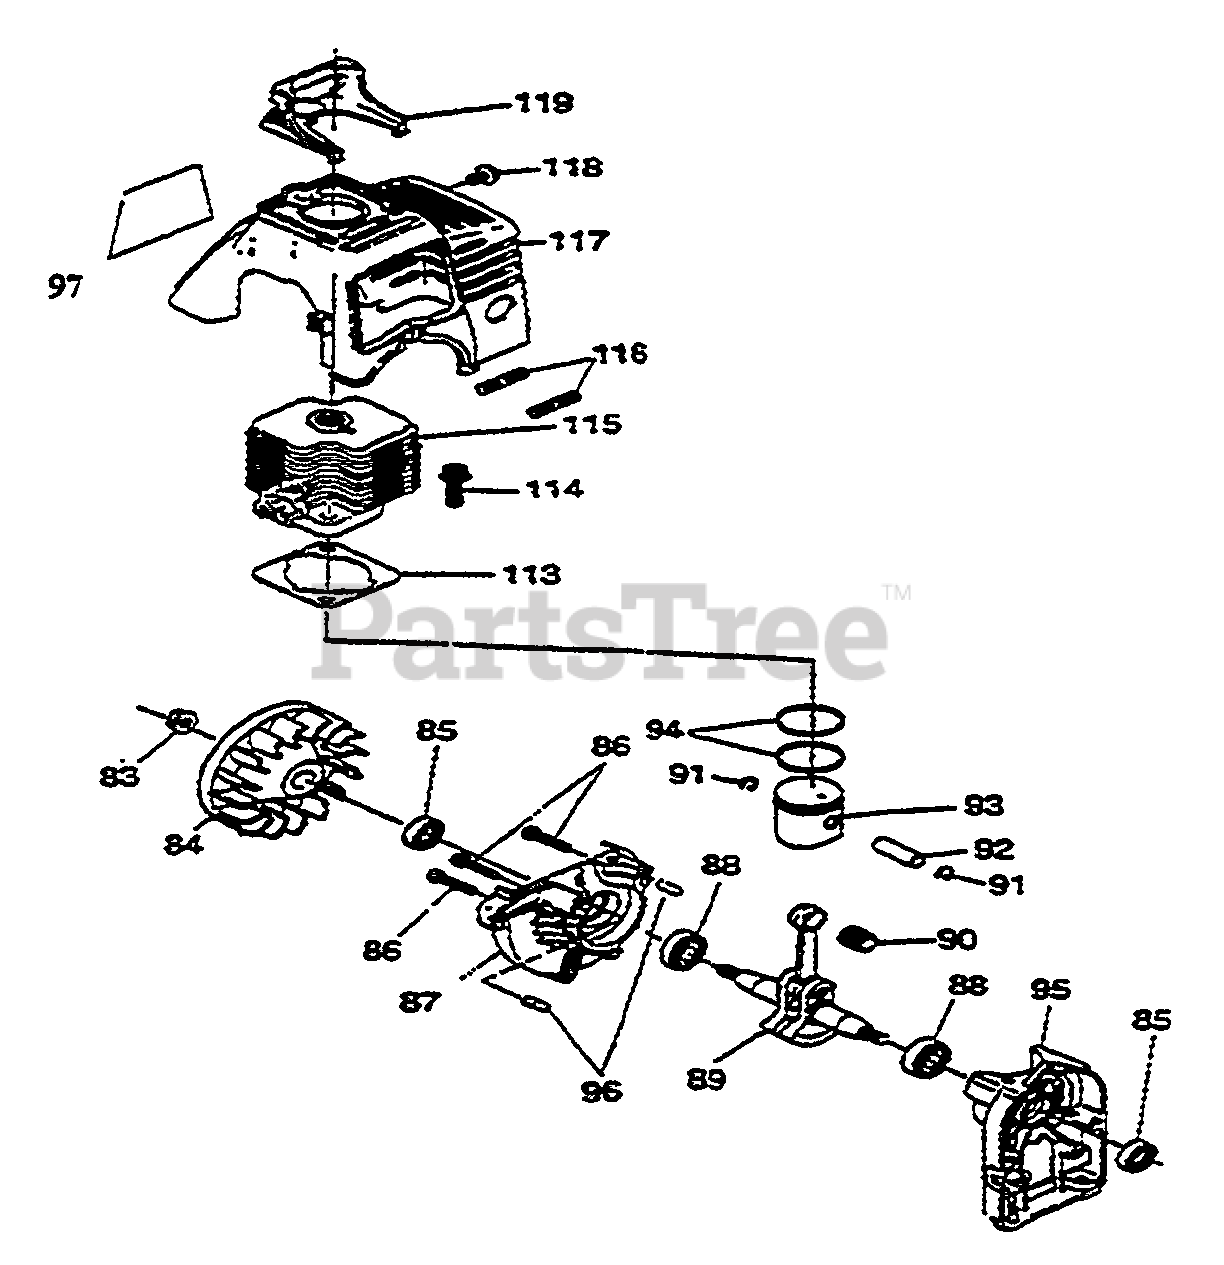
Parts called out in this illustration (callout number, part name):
83	NUT, CONICAL SPG.
85	OIL SEAL
87	CASE DRIVE
88	BEARING, BALL
89	CRANKSHAFT ASSY
90	BEARING,NEEDLE
91	CLIP, PISTON PIN
92	PIN, PISTON
94	RING, TOP
95	CASE, STARTER
96	DOWEL PIN
113	GASKET, CYLINDER
114	BOLT, FLANGE
116	BOLT, STUD
117	COVER, TOP
118	SCREW & WASHER
119	GUARD, SPARK PLUG
